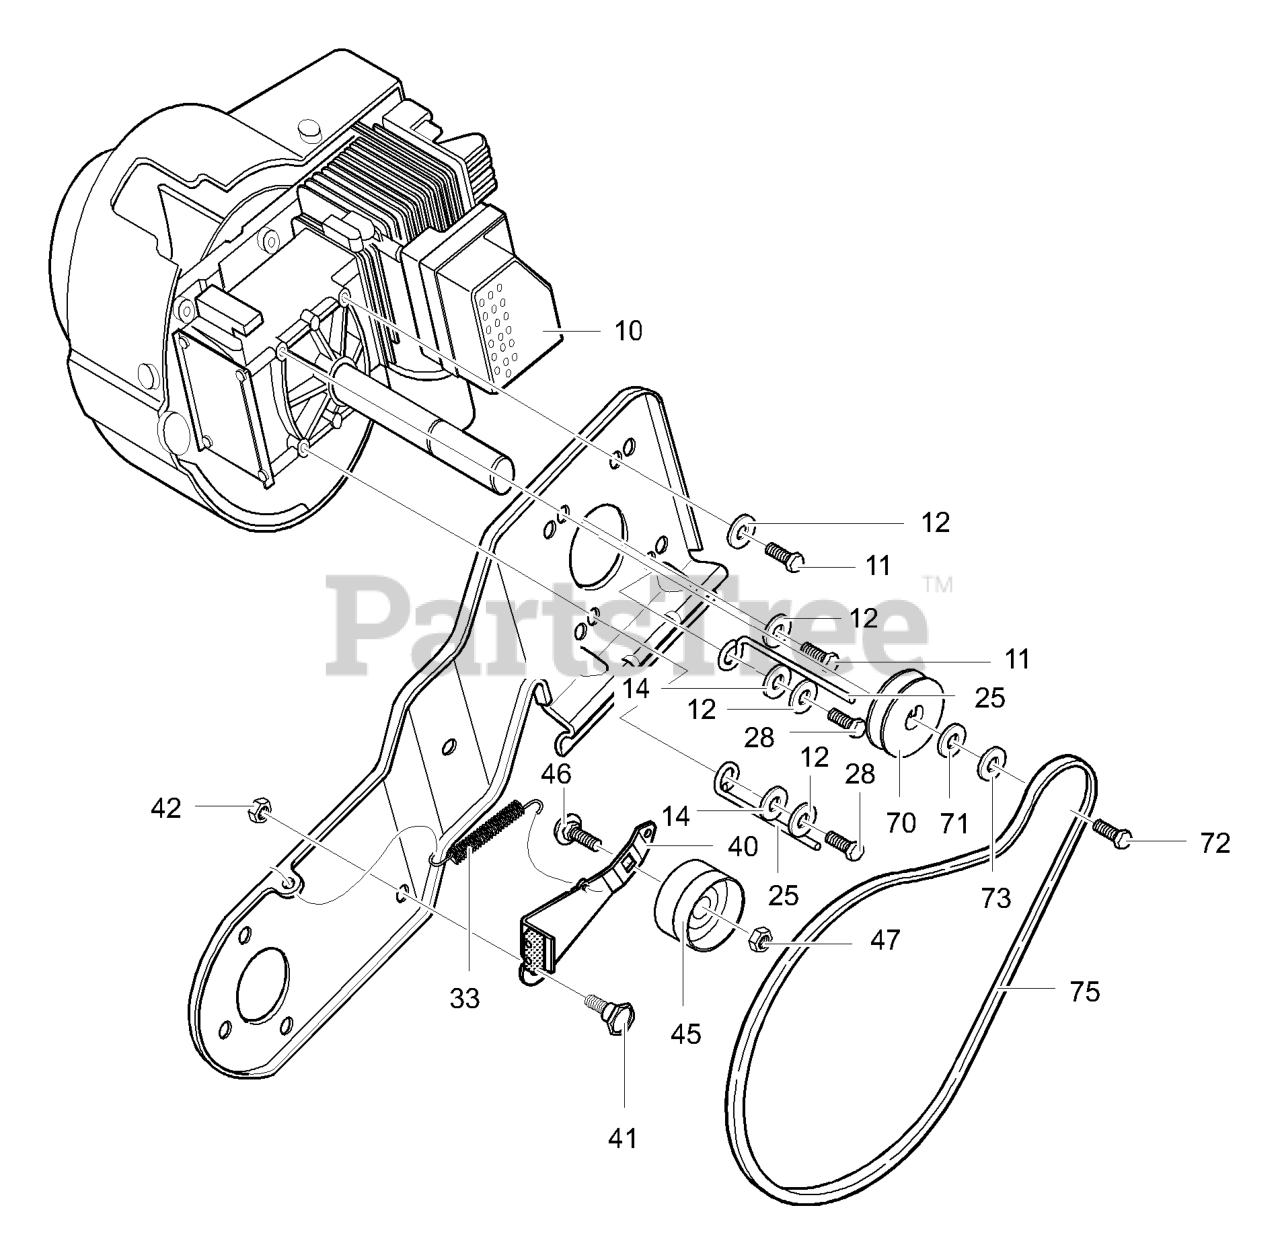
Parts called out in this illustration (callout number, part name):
10	ENGINE
11	SCREW, 5/16-18 x 0.75
12	WASHER, SPTLK
14	FLATWASHER
25	BELT GUIDE
28	SCREW, 5/16-18 x 1.00
33	SPRING, IDLER BRAKE
40	IDLER ARM
42	NUT
45	PULLEY, IDLER
47	NUT
70	PULLEY, V 3L
71	WASHER
72	SCREW, 5/16-24 x .75
73	WASHER
75	BELT, V 3L 34.8" STEEL
